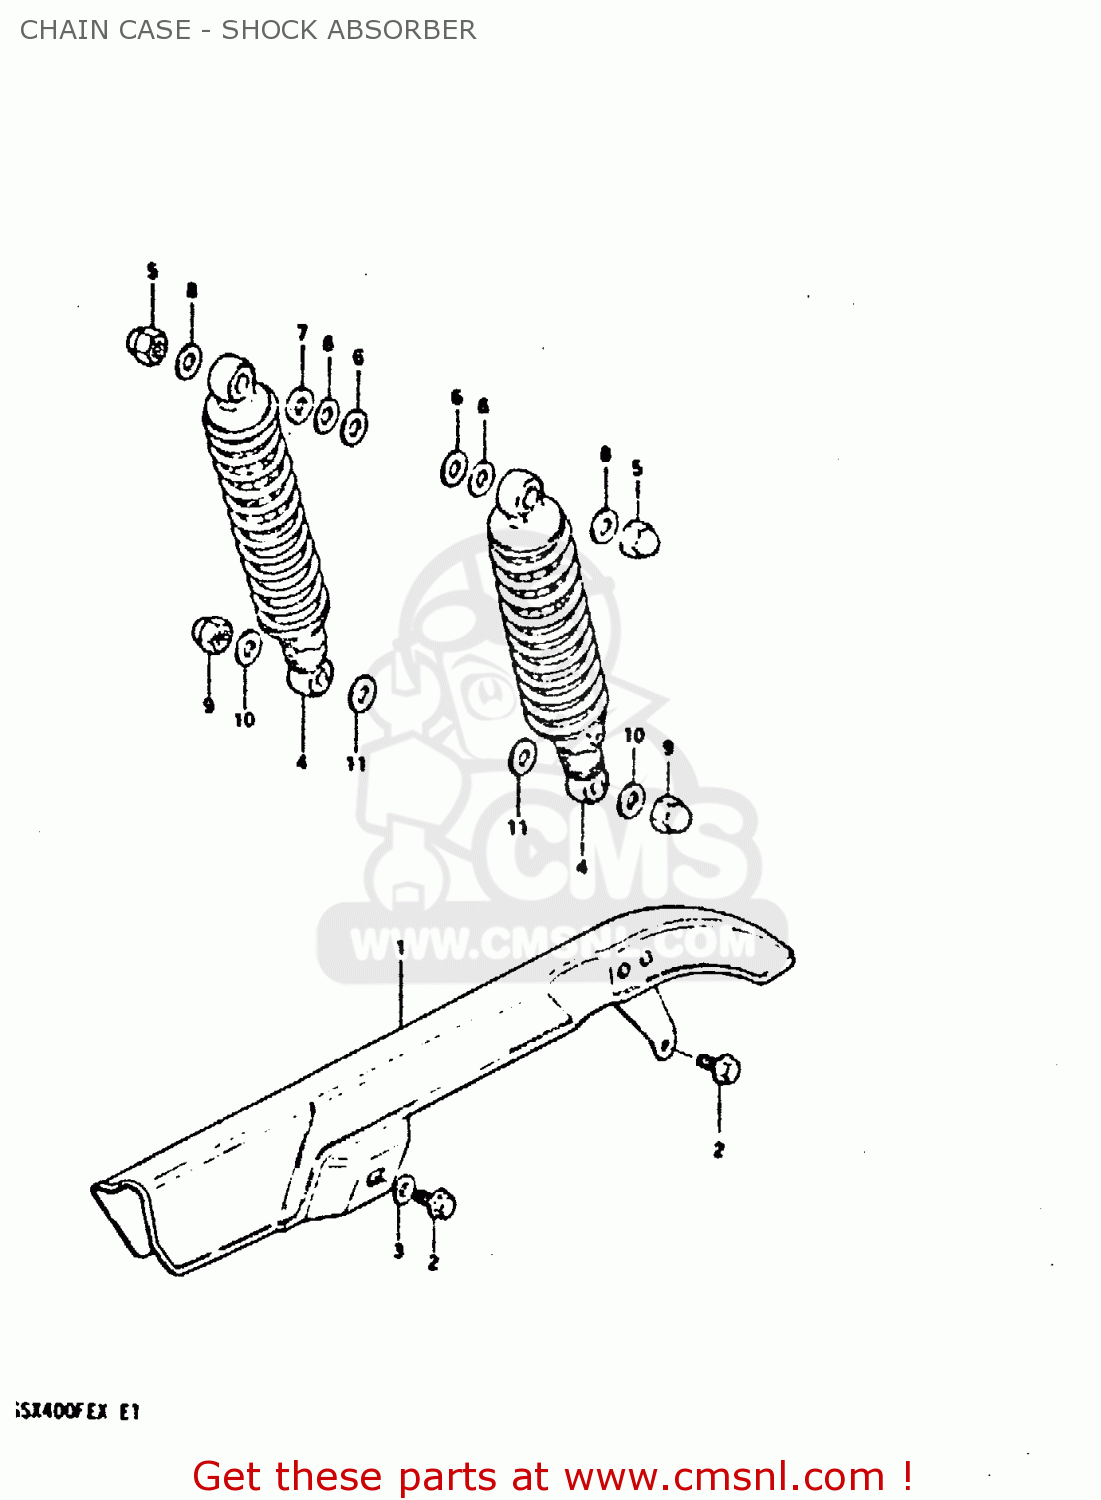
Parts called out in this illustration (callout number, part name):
1	CHAIN CASE
2	BOLT
3	WASHER
4	SHOCK ABSORBER, REAR
5	NUT
6	WASHER
7	WASHER (12.5X24X3.2)
8	WASHER
9	NUT, LOWER LH
10	WASHER
11	WASHER (12.5X24X1.6)
